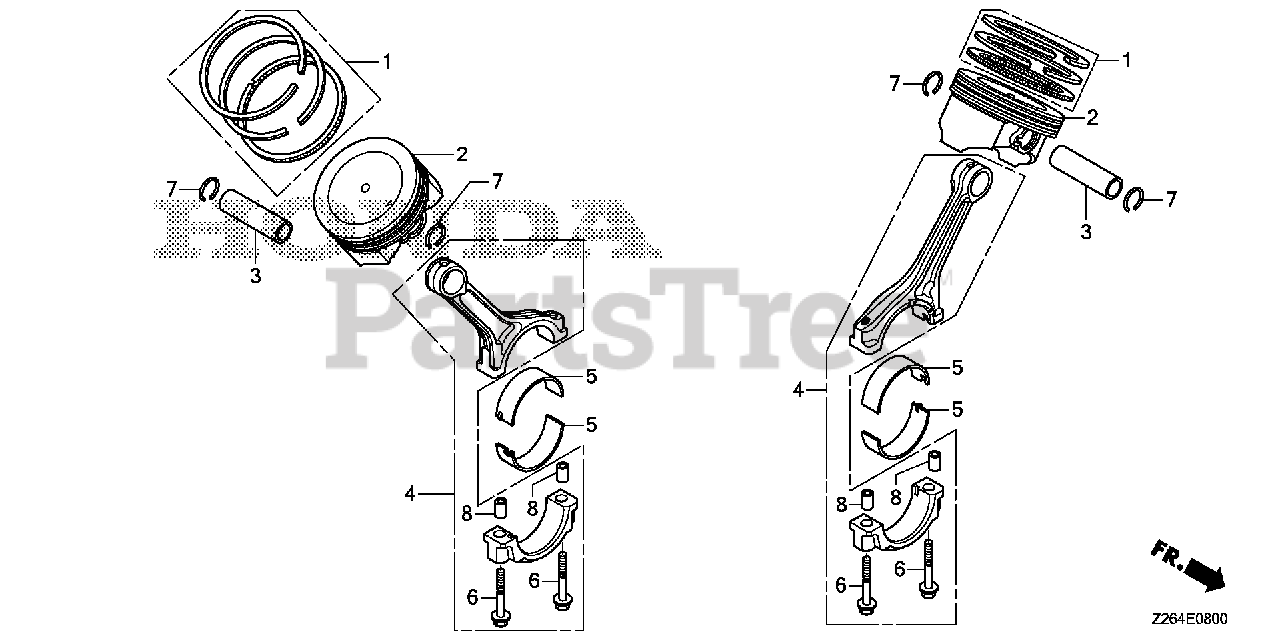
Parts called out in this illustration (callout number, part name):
1	RING SET, PISTON (STD) (TEIKOKU)
2	PISTON
3	PIN, PISTON
4	ROD ASSY., CONNECTING
5	BEARING A, CONNECTING ROD
6	BOLT, CONNECTING ROD (7X38)
7	CLIP, PISTON PIN (18MM)
8	PIN, DOWEL (9X10)
